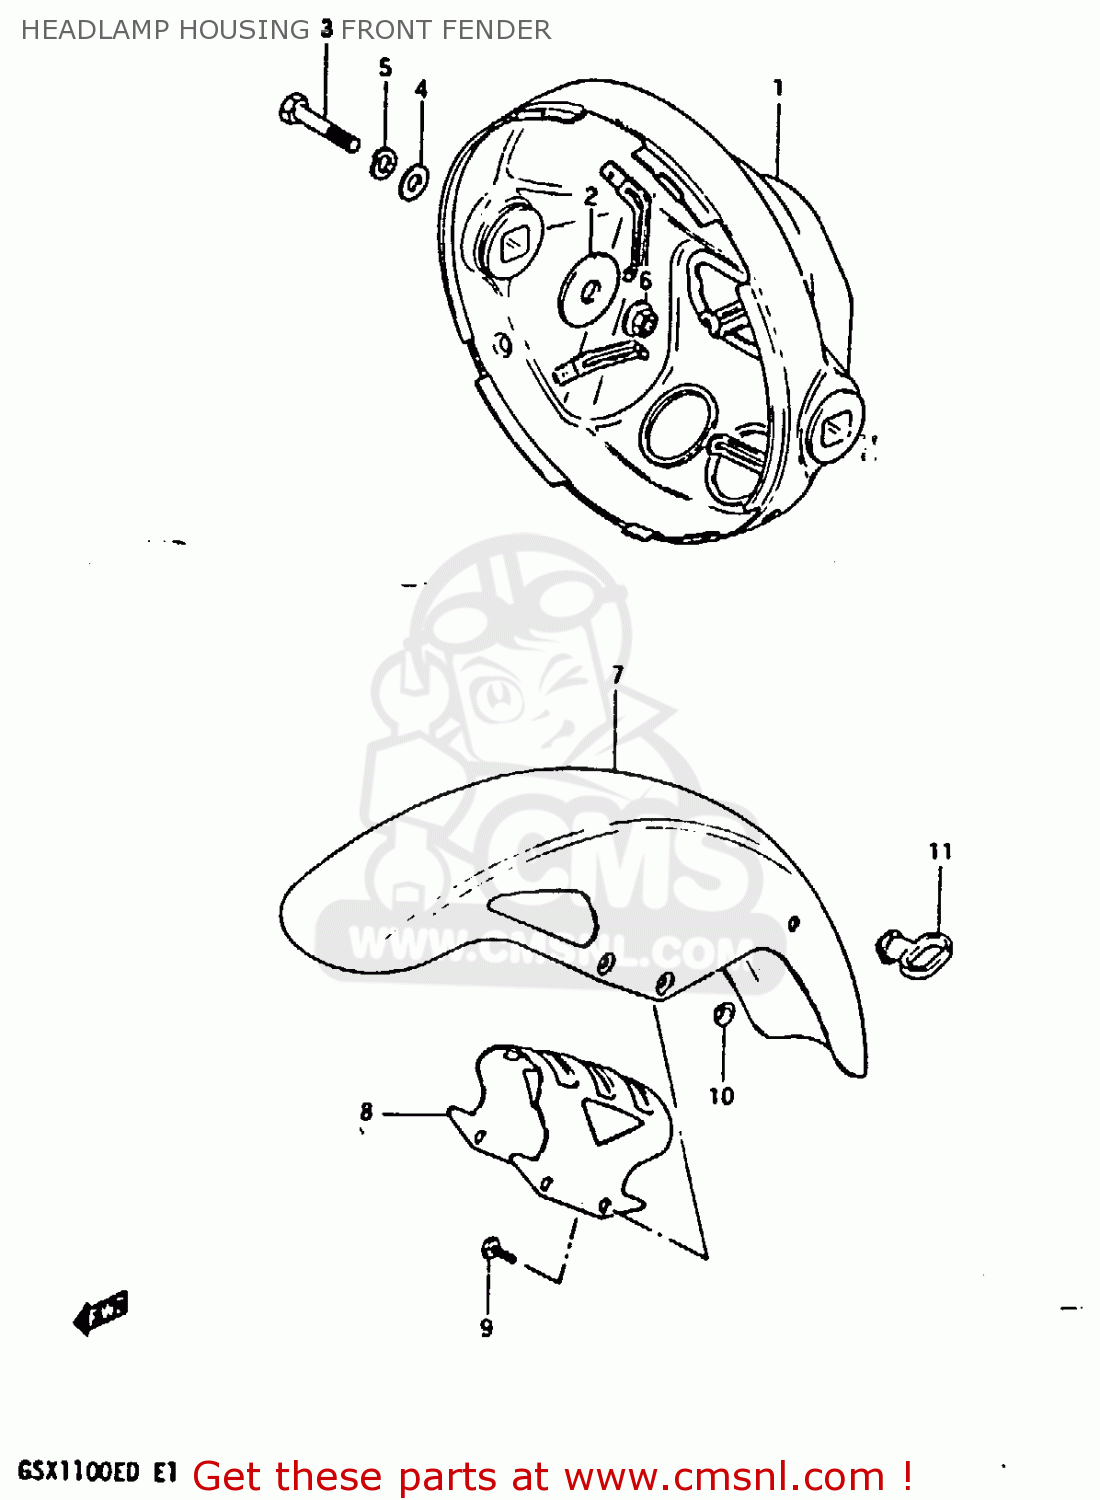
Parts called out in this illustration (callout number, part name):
1	HOUSING,HEADLAMP
2	WASHER (8.5X29X1.6)
3	BOLT
4	WASHER
5	LOCK WASHER
6	NUT
7	FENDER,FRONT
8	BRACE,FRONT FENDER
9	BOLT 8X16
10	WASHER
11	GUIDE,CABLE
